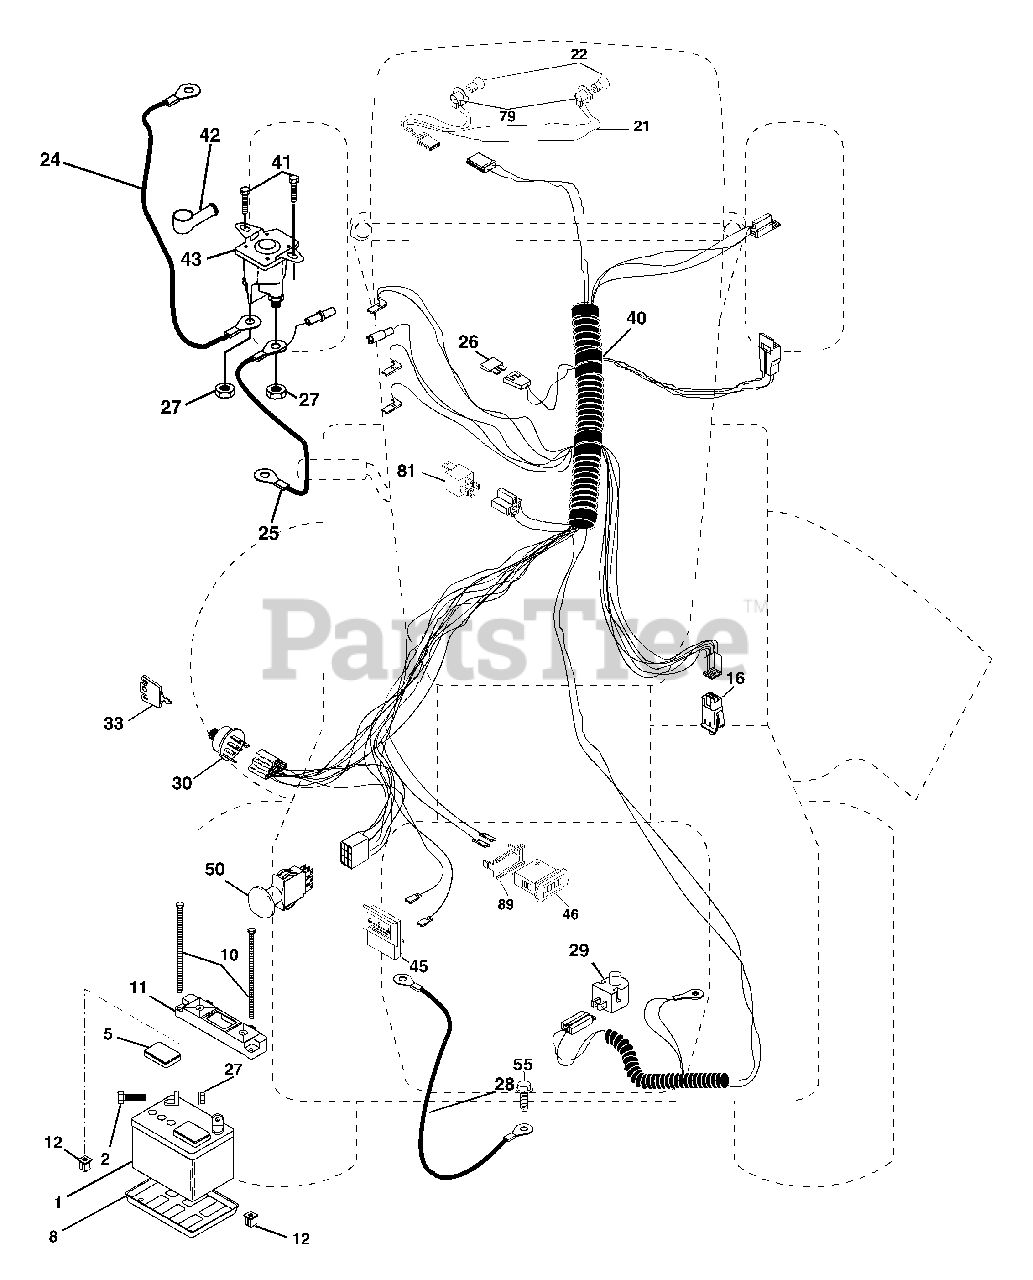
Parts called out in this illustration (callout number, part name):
1	Battery
2	Bolt Hex Hd 1/4-20 UNC X 3/4
8	Tray, Battery
10	Bolt, BTR FRT 1/4-20 x 7.5
11	Hold Down Battery, Front
12	Nut, Push, Nylon
16	Switch Interlock Push-In
21	Harness Asm Light W/Bulbs
22	Bulb Light
24	Cable Battery
25	Cable Batterywire
26	Fuse
27	Nut Keps Hex 1/4-20 Unc
28	Cable Ground
29	Switch Plunger Normal OP Olive
30	Switch Ign 4 pos w/lights
33	Key Ign
40	Harness Ign.
41	Bolt Blk Fin Hex 1/4-20 x 1/2
42	Cover Terminal Red
43	Solenoid
45	Ammeter Rectangular
46	Hourmeter Snap-In
50	Switch, PTO
55	Screw Thdrol 5/16-18 x 1/2
79	Bulbholder
81	Relay Asm
89	Bracket Snap-In Hourmeter
